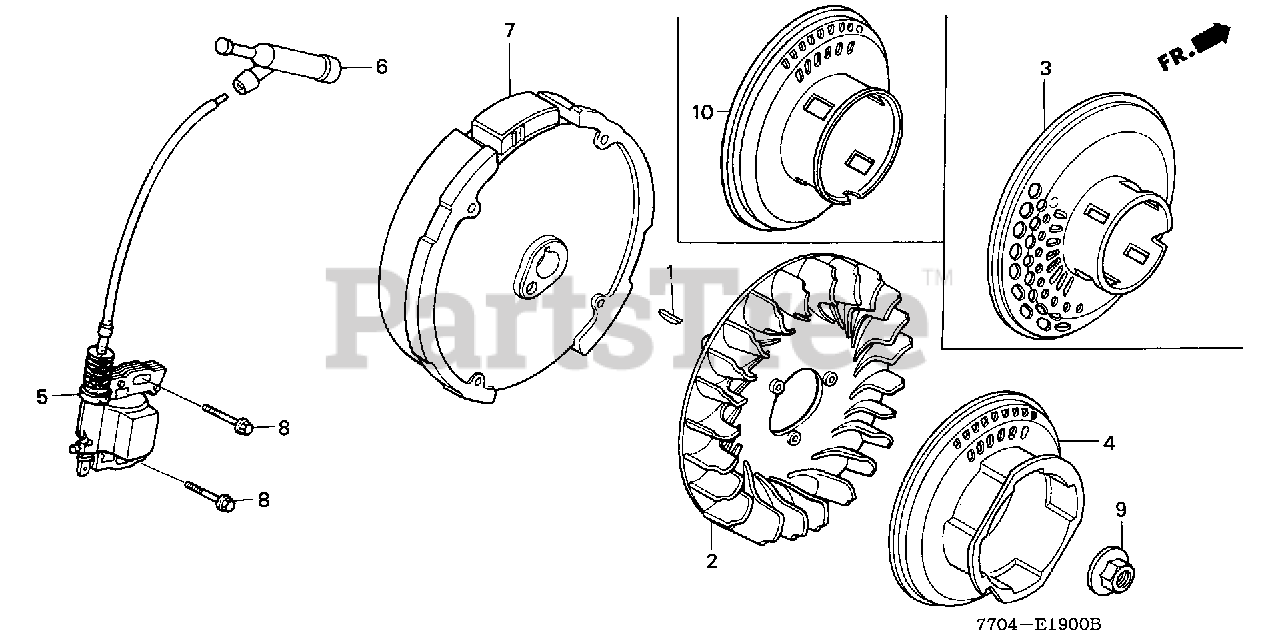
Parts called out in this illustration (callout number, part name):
1	KEY, SPECIAL WOODRUFF (25X18)
2	FAN, COOLING
3	PULLEY, STARTER (SCREEN GRID)
5	COIL ASSY., IGNITION
6	CAP ASSY., NOISE SUPPRESSOR (NICHIWA Y-EZ RTFM256)
8	BOLT, FLANGE (6X28) (CT200)
9	NUT, SPECIAL (16MM)
